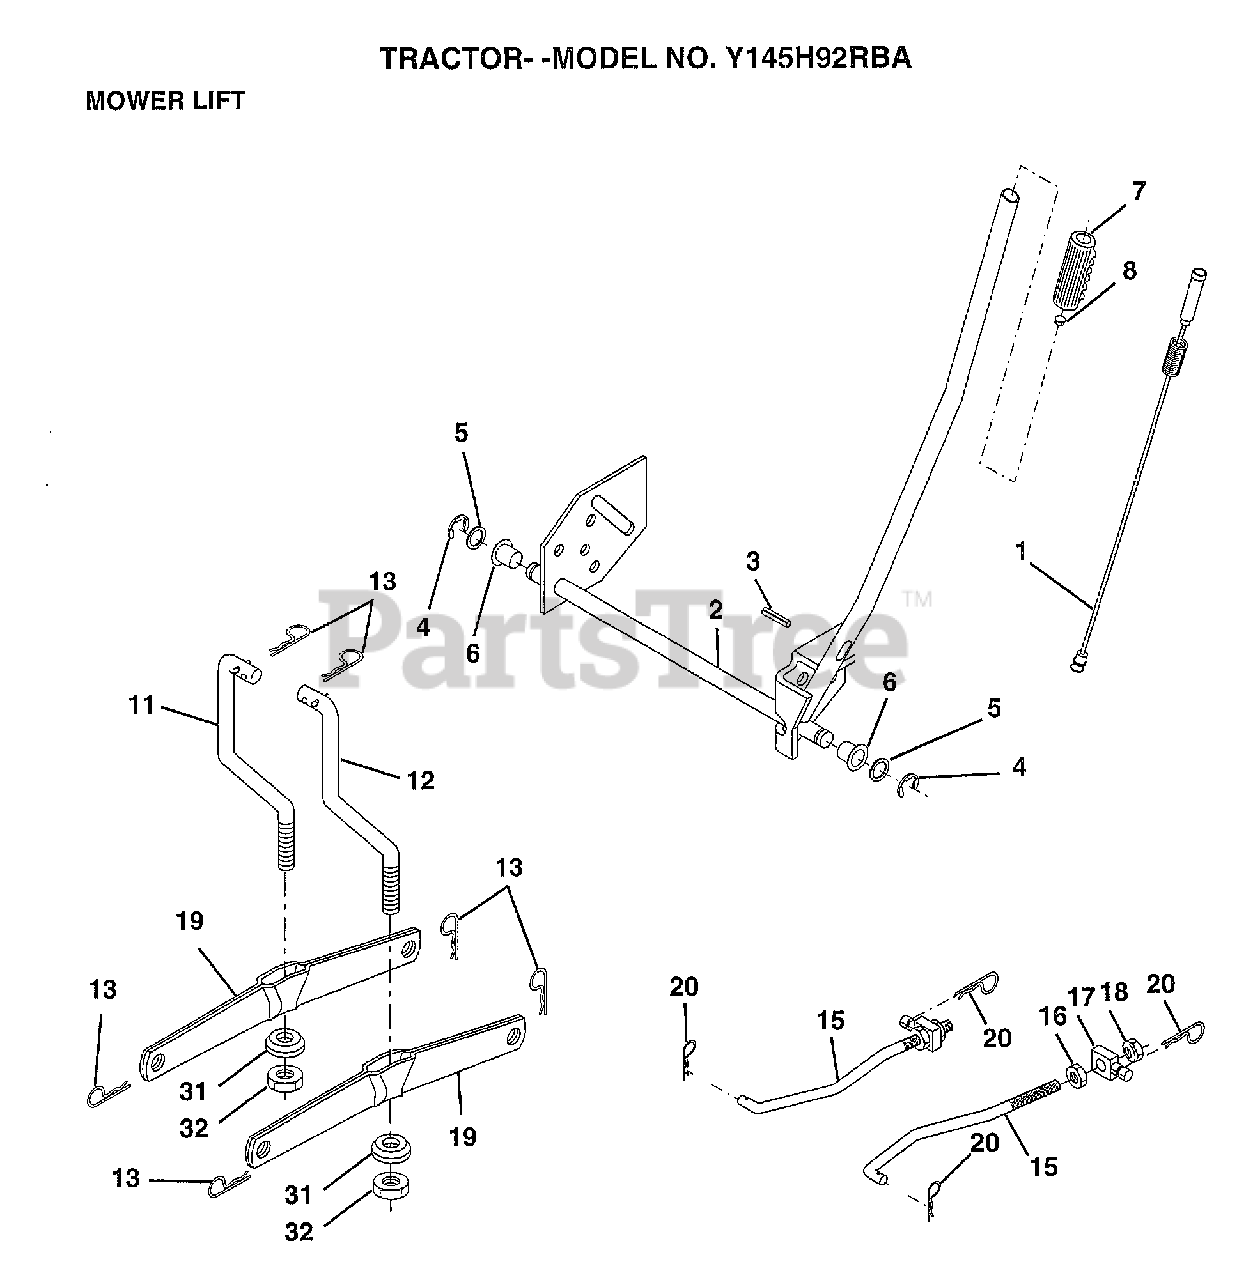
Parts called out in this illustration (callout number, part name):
1	WIRE ASM W.SPRING
2	"SHAFT ASM LIFT,RH"
3	PIN-GROOVE LT
5	WASHER
6	NYLON BEARING
7	GRIP
11	LINK.LIFT.LH.CRD
12	LINK.LIFT.RH.CRD
15	LINK.FRONT
16	NUT
17	TRUNION
18	NUT LTV
19	ARM SUSP REAR
20	RETAINER SPRING
31	BEARING PVT LH
32	NUT.CROWNLOCK.3/8
